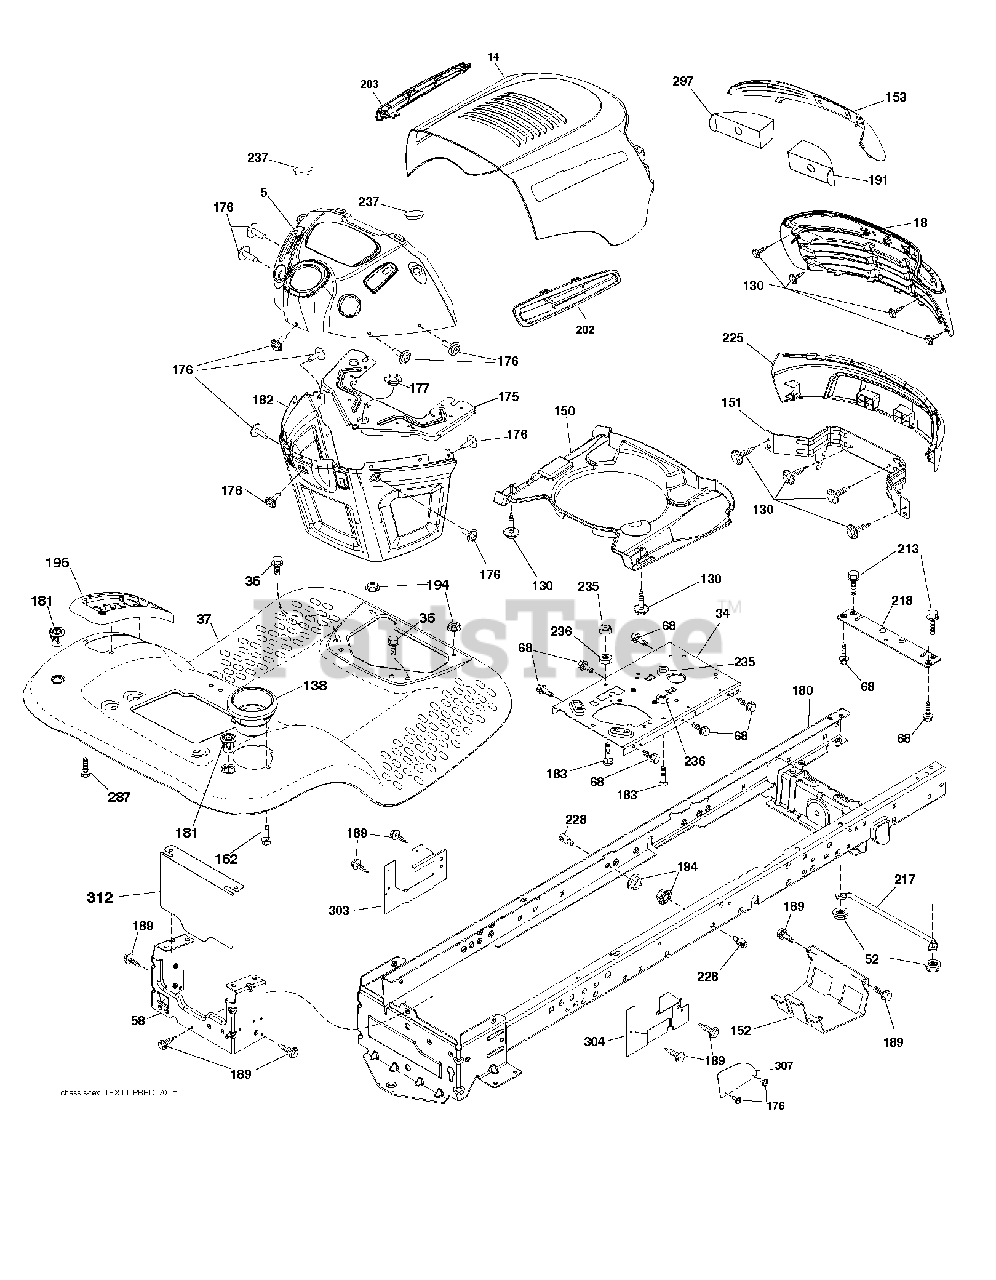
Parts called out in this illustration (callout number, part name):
5	DASH.LT.PRED.E.SRV.CKMTC.BLK
14	HOOD.PNT.PREDATOR.LT.TX.667
18	GRILLE.SVC.BASE.PREDATOR.LT428
34	Engine Welded Chassis Plate
36	SCREW 5/16"
37	FENDER.TLT.PDL.CNTRL.W/CPH.667
52	LOCKNUT
58	DRAWBAR UPPER 2PC SMALL FENDER
68	SCREW LT
130	SCREW.#10 X 0.750.BOS THREAD
138	CUPHOLDER.TL.TEX.BLACK
150	DUCT.AIR.PREDATOR.LT.2.36"
151	BRACKET.PIVOT.ALPHA.LT
152	SHIELD BROWNING
153	LENS.PREDATOR.LT
162	SCREW.HI-LO.CONSOLE
176	SCREW.#10-24X5/8.RN.QU
177	BUSHING STEERING
180	CHASSIS.WLDMNT.14GA.2PC.18".TI
181	FEND/FTRST.PCH.CPH.NFW
182	DASH.LWER.PREDATOR/HUSQ.LT
183	BOLT.5/16-18X1-1/4 FULL THD
189	SCREW
191	INSERT.REFLECT.PREDATOR.LT.RH
194	NUT LOCK HEX FLANGE 5/16-18
196	CONSOLE.ASM.DECKLFT.BL/RBT.TLT
203	VENT.SIDE.PRED.LT.LH.JONSERED
213	BOLT
217	ROD.PIVOT.HOOD
218	X-PIECE.HOOD.STOP.NON/
225	BUMPER.GRILLE.PRED.LT.JONS.505
228	STUD.FASTNER.W/ANTI-ROTATE
235	SPACER FENDER
236	NUT.CENTERLOCK.5/16-
237	PLUG.MOUNT.CARGO.BLK
297	REFLECTOR.INSERT.PRED.LH.LT
303	SHIELD CHASSIS LEFT
307	SHIELD UPPER PEDAL
312	SHIELD.PNT.DRAWBAR.FRENCH
